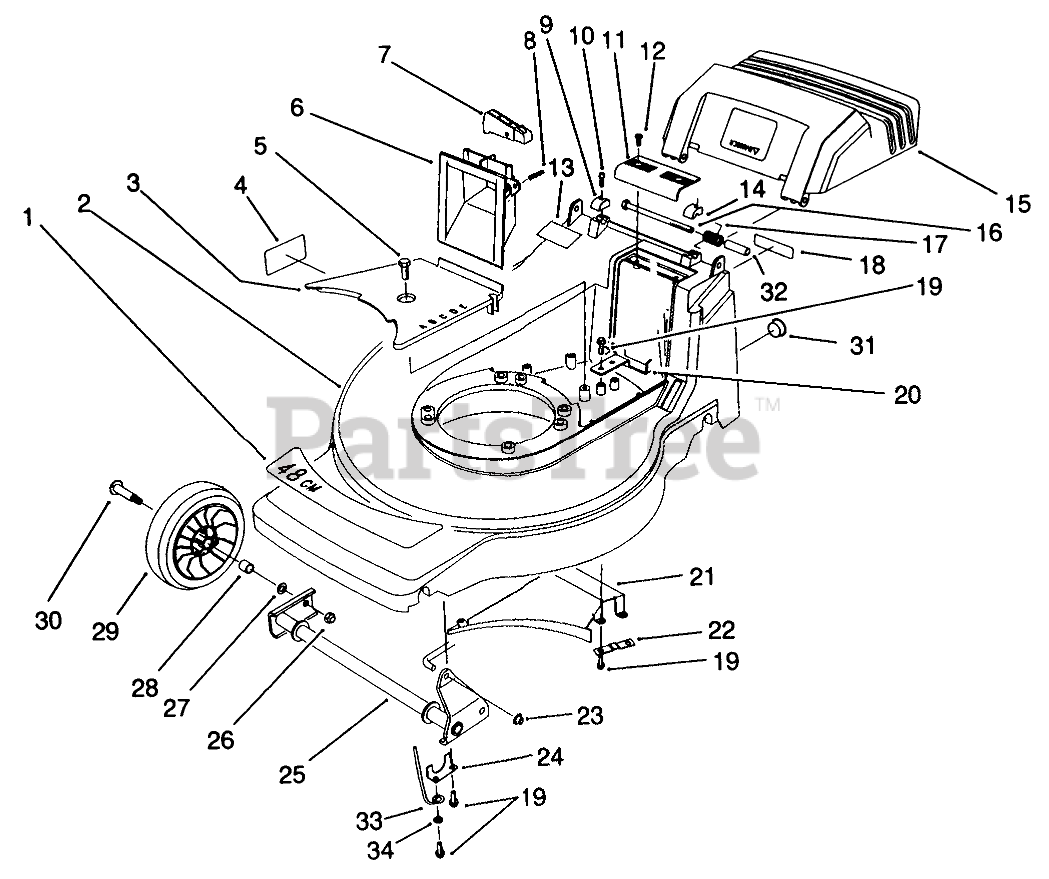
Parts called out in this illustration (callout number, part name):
1	DECAL - DECK
2	Housing-48cm (Incl. Ref. #4, & 13)
3	BELT COVER
4	Decal Danger
5	SCREW-HWHTF
6	GRIP - LOWER
7	TRIGGER - HOC
8	PIN-SPIRAL
9	CAP-HINGE BOLT, RH
10	SCREW-HSH
11	GRIP-UPPER
12	SCREW-PPH, PLASTITE
13	Decal-Noise
14	CAP-HINGE BOLT, LH
15	Door-Discharge
16	SCREW-HH
17	DOOR SPRING
18	DECAL FRENCH REGUL.
19	SCREW-HWHTF
20	REAR BELT GUIDE
21	Ramp-Discharge
22	Strap-Rear Suspension
23	NUT-PUSH
24	FRONT SECURING PLATE
25	FRONT PIVOT WA
26	Nut
27	WASHER
28	BUSHING
29	Wheel & Tire Assembly (Incl. Ref. #28)
30	BOLT-WHEEL
31	DOME PLUG (DP-1000)
32	SPACER-DOOR
33	LH AXLE RETAINER
34	WASHER-FLAT
